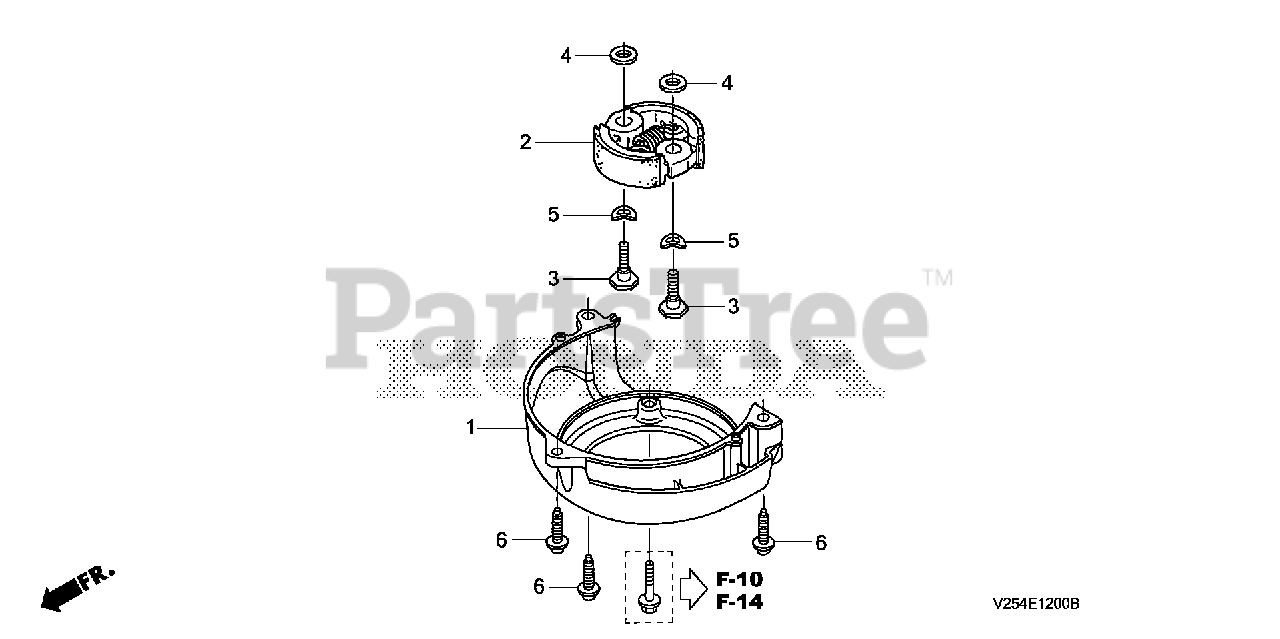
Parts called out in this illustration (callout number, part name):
1	COVER, FAN
2	CLUTCH ASSY.
3	BOLT, CLUTCH (6MM)
4	WASHER, CLUTCH (6X15)
5	WASHER, WAVE (8MM)
6	BOLT, SOCKET (5X20)
